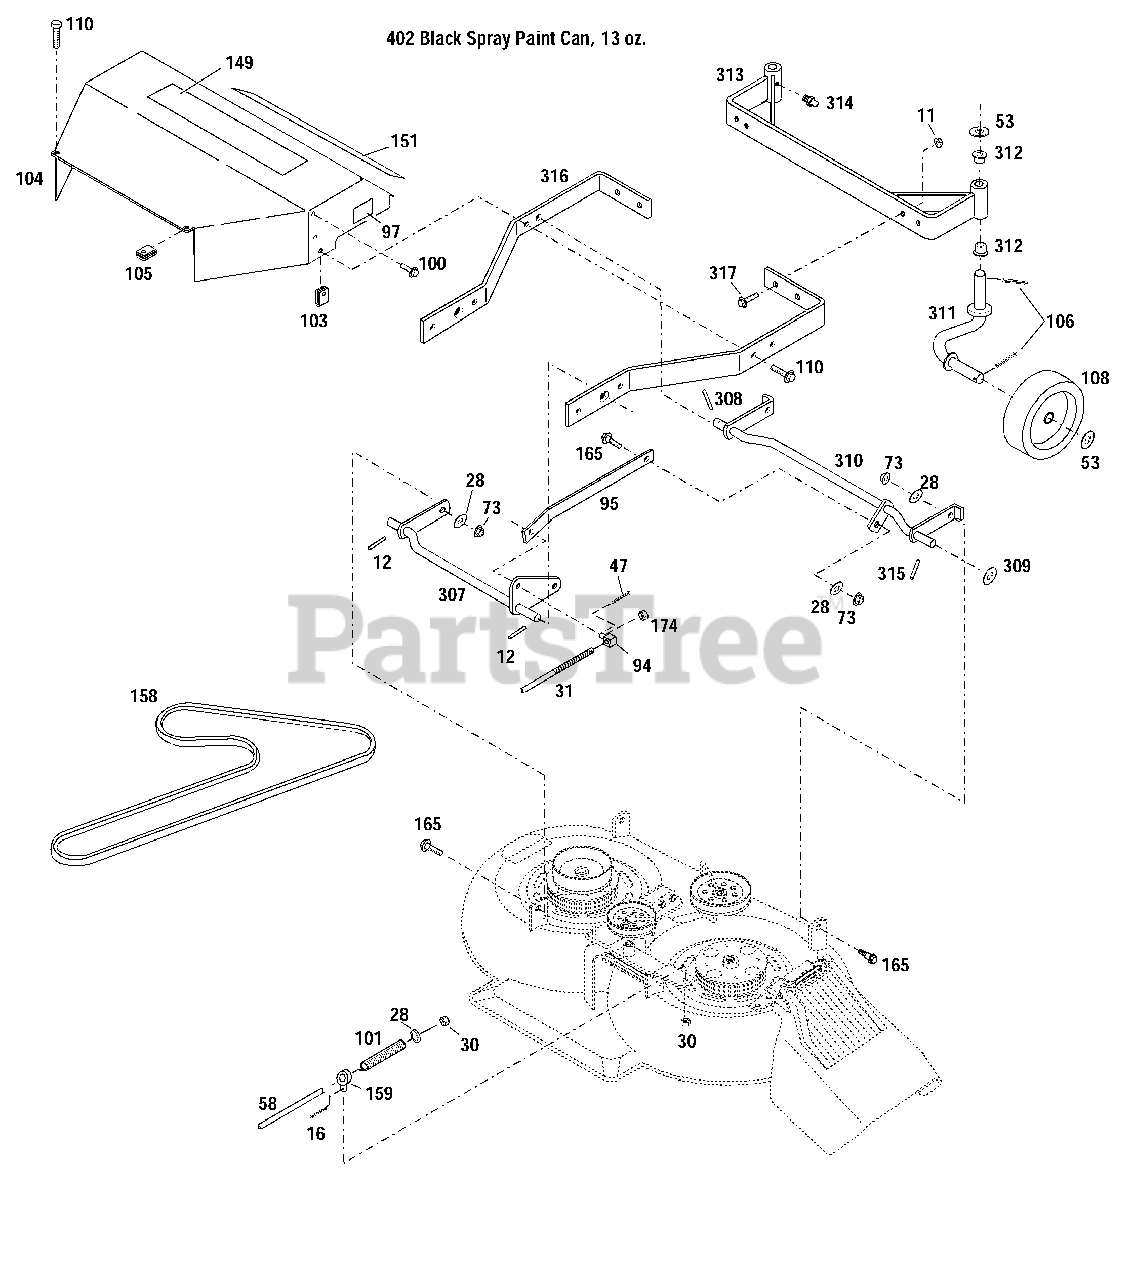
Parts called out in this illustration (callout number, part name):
11	Flange Locknut, 3/8-16
12	Cotter Pin, 1/8 x 1
16	Cotter Pin, 3/32 x 5/8
28	Flat Washer, 3/8
30	Locknut, 3/8-16
31	Lift Crank
47	Cotter Pin
53	Special Washer
58	Lower Blade Rod
73	Flange Locknut, 3/8-16
94	Pivot Block
95	Leveler Bar
97	Cutting Height Decal
100	Tap Screw, #8 x 3/8
101	Compression Spring
103	Speed Nut, 5/16-18
104	Belt Guard
105	Speed Nut, 5/16-18
106	Cotter Pin
108	Gage Wheel
110	Flange Lock Screw, 5/16 x 3/4
149	Logo Decal
151	33" Combination Deck Decal
159	Eye Bolt
165	Shoulder Bolt
174	Toplock Nut
307	Rear Lift Assembly
308	Roll Pin, 1/4 x 1
309	Flat Washer, 5/8
310	Front Lift Assembly
311	Spindle Assembly
312	Flange Bearing
313	Gage Support
314	Grease Fitting
315	Drive Pin, 1/4 x 3
316	Mower Support
317	Whizlock Screw, 3/8-16 x 1
402	Black Spray Paint Can, 13 Oz.
